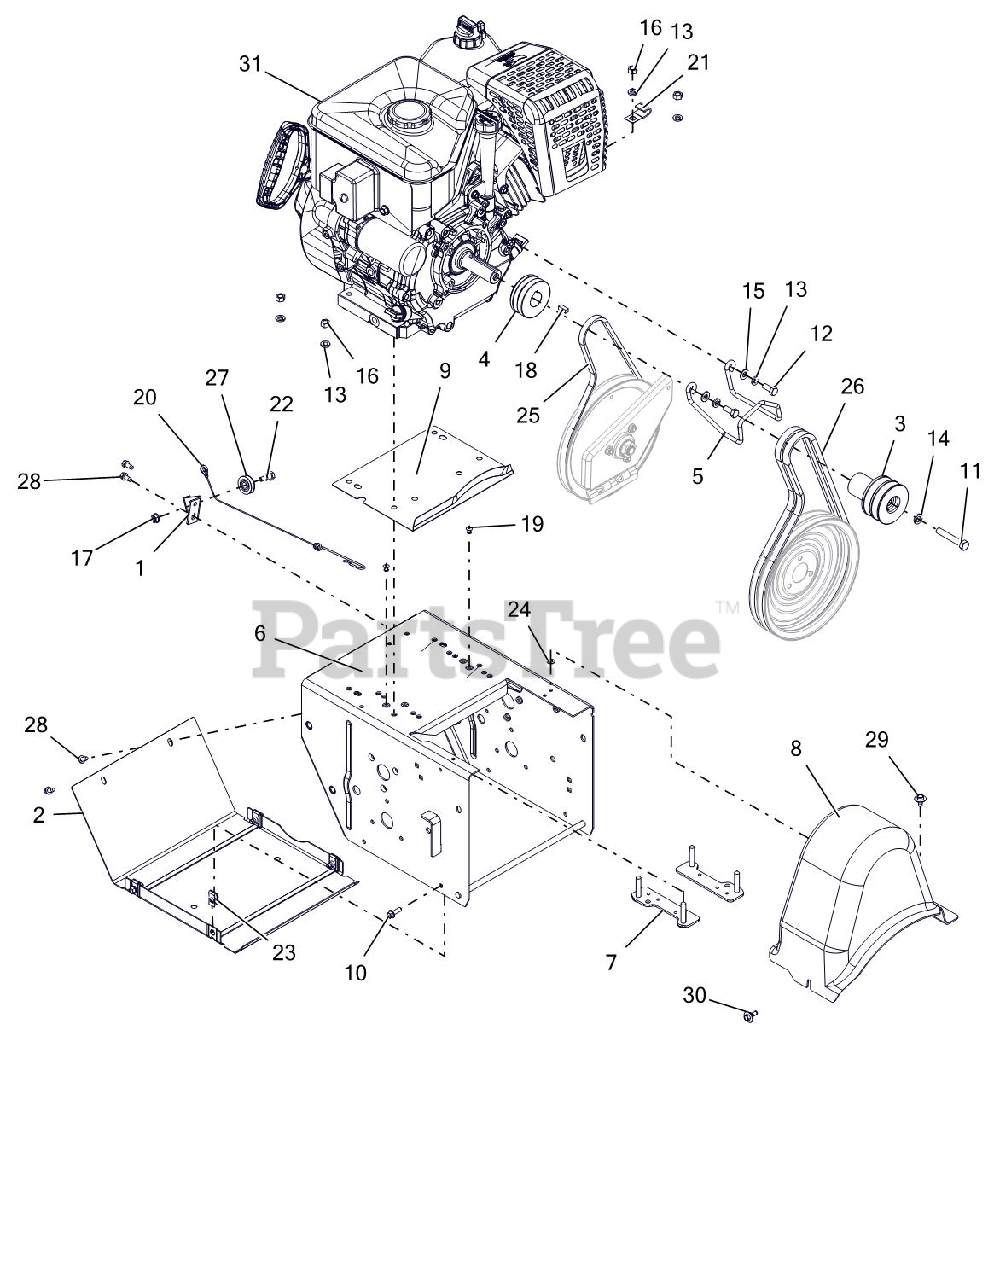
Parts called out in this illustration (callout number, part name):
1	BRACKET, CABLE PULLEY
2	COVER, BOTTOM
3	SHEAVE, ATTACHMENT 2-GRV
4	SHEAVE, DRIVE
5	FINGER, BELT
6	FRAME, MAIN-DELUXE(WELDMENT)
7	STRAP, BOLT-LARGE
8	COVER, BELT-LARGE
9	BAFFLE, WATER - LARGE BLOCK
10	BLT-HEX .25-20X.75 HWH YZ GR5
11	BLT-HEX .38-24X2.25 YWZC GR5
12	BLT-HEX .31-24X.75 YWZC GR5
13	WSHR-LK .312X.097 HVY YWZC
14	@WSHR-LK .38X.094 REG YWZC
15	@WSHR-FL-STL.344X.688X.065YWZC
16	@NUT-HEX .31-18 YWZC
17	@NUT-LK-TOP-FLG .25-20 YWZC
18	KEY-SQ .25X.625X.25 SAE 8630
19	RVT-POP .187 YZ
20	CABLE, LOWER TRACTION,SS & PRO
21	J-CLAMP
22	BOLT, SHLDR-.375X.375X.25-20
23	NUT-RTNR .25-20X.56
24	NUT-PUSH .25X.50 O.D.
25	V-BELT, 3L-WRAPPED
26	V-BELT, HA-RAW EDGE (SET)
27	PULLEY, CABLE
28	SCR-TAP .25-20X.50 HWH TR YWZ
29	SCR-TAP .25-20X.50 LGHWH TR YZ
30	SCR-TAP .25-20X.5 CAPTIVE
31	ENGINE, AX369 GEN 3 120V/60W
